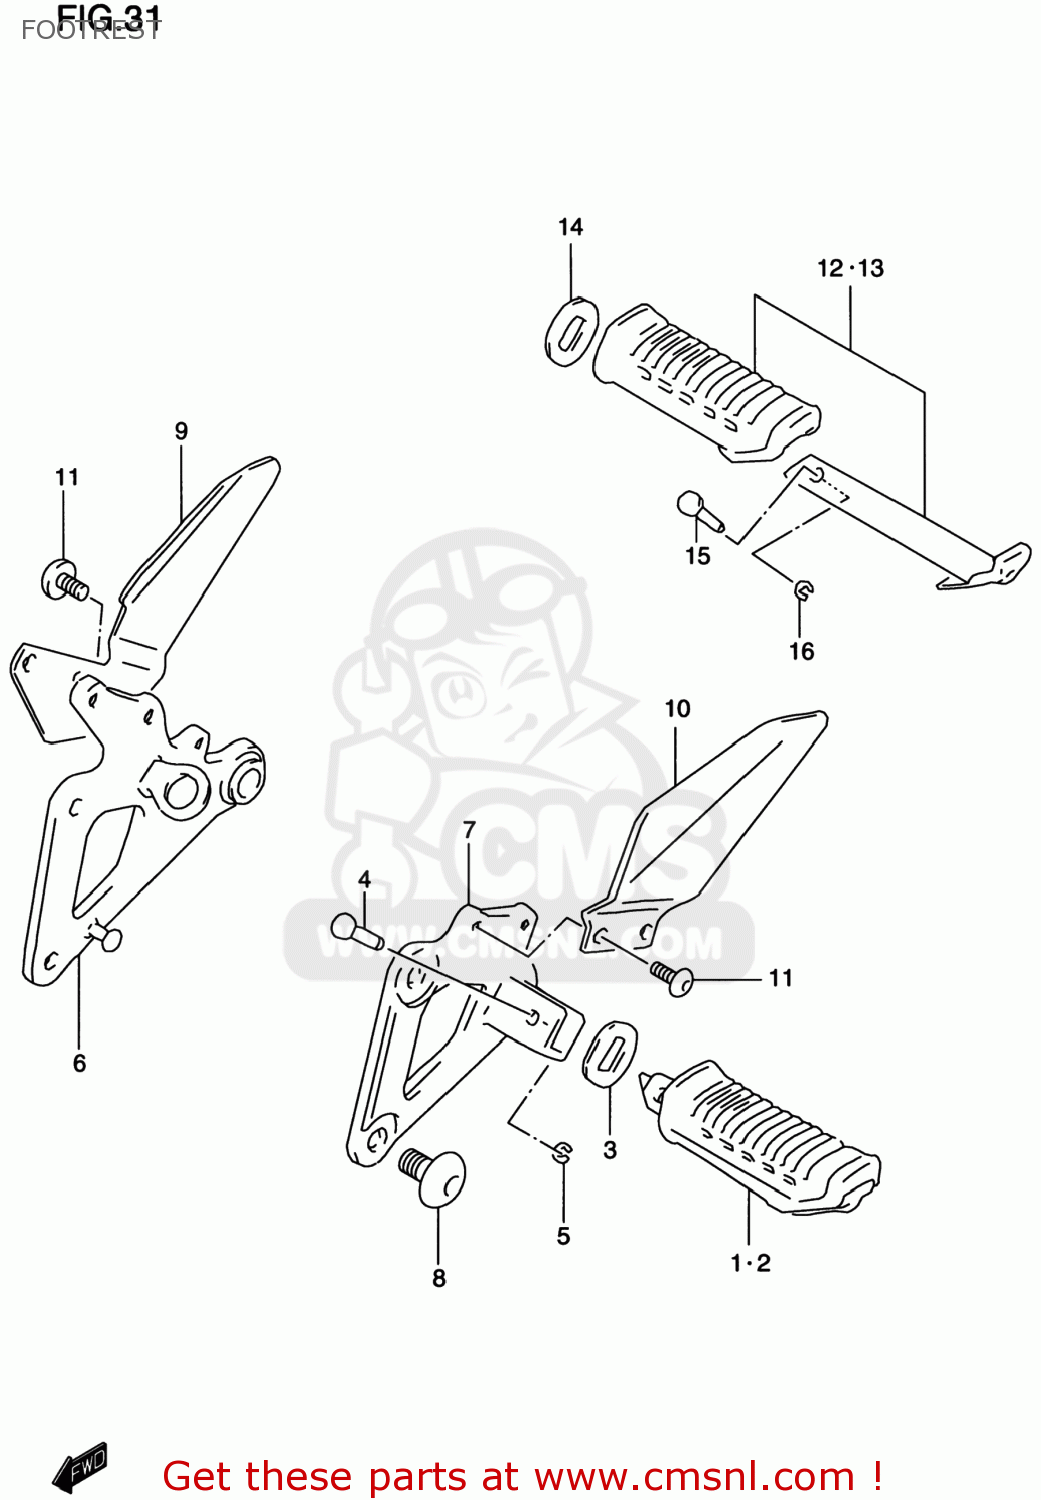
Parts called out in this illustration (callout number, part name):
1	RUBBER,FR FOOTREST,R
2	RUBBER,FR FOOTREST,L
3	WASHER,FOOTREST RUBBER
4	PIN
5	E-RING
6	BRACKET,FR FOOTREST,R
7	BRACKET,FR FOOTREST,L
8	BOLT(8X20)
9	GUARD,FR FOOTREST,R
10	GUARD,FR FOOTREST,L
11	SCREW(6X12)
12	FOOTREST ASSY,PILLION,R
13	FOOTREST ASSY,PILLION,L
14	WASHER,FOOTREST RUBBER
15	PIN
16	E-RING
